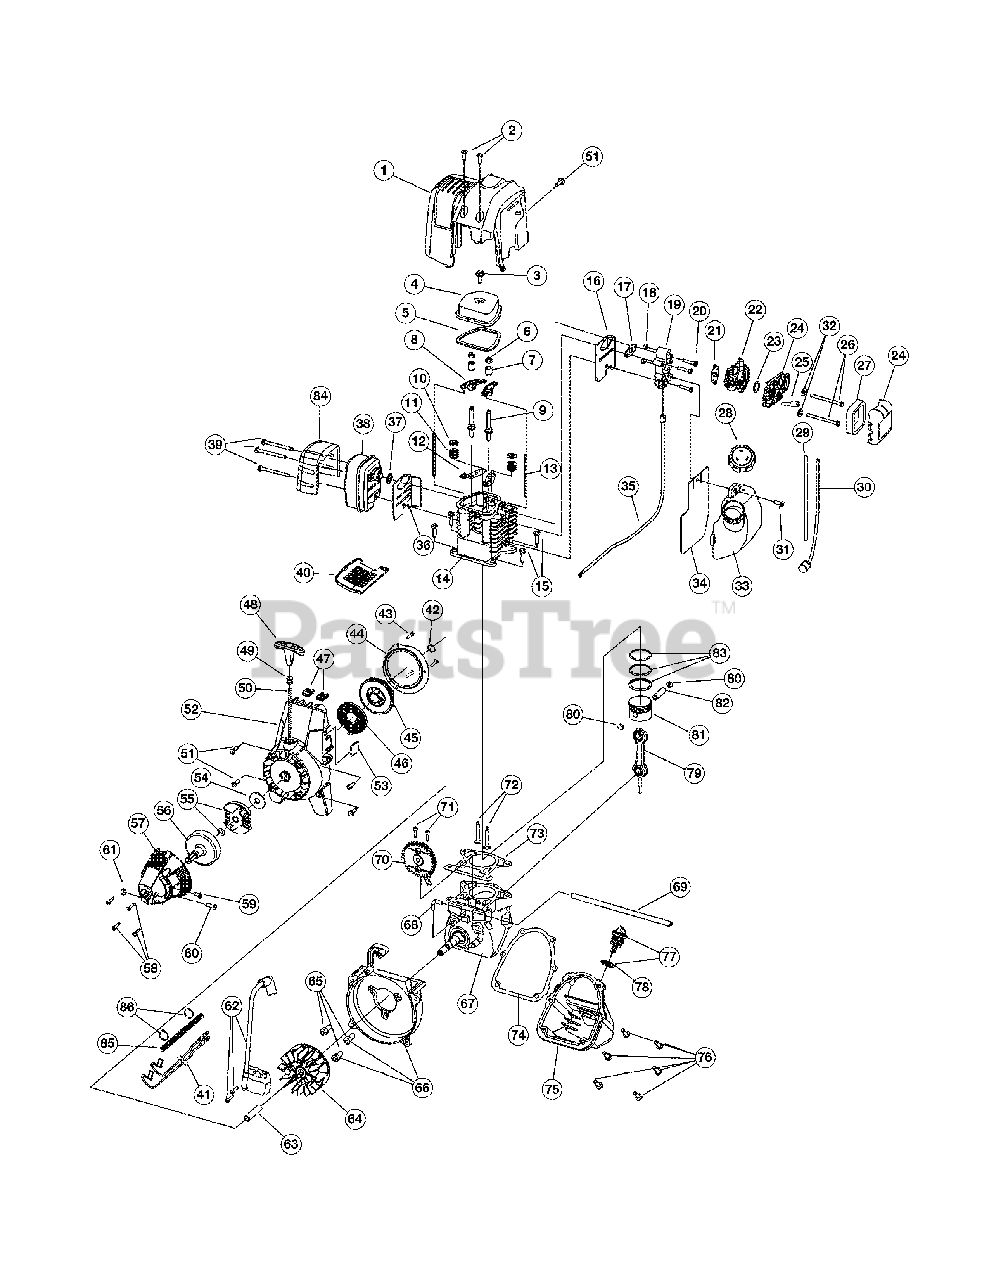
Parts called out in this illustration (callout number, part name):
1	Engine Cover
2	Engine Cover Screws
3	Valve Cover Screw
4	Valve Cover
5	Valve Cover Gasket
6	Rocker Adjustment Nut
7	Rocker Arm Pivot
8	Rocker Arm
9	Rocker Arm Stud
10	Valve Spring Retainer
11	Valve Spring
12	Push Rod Guide
13	Push Rod
14	Cylinder Assembly
15	Cylinder Screw
16	Intake Baffle Gasket
17	Carburetor Mount Gasket
18	Nut
19	Carburetor Mount
20	Carburetor Mount Screw
21	Carburetor Gasket
22	Carburetor w/Primer
23	O-Ring, Carburetor
24	Air Filter Cover Assembly
25	Breather Tube
26	Air Filter Mounting Screw
27	Air Filter
28	Fuel Cap
29	Fuel Return Line
30	Fuel Pick-Up Line with Filter
33	Fuel Tank Assembly
34	Fuel Tank Shield
35	Throttle Cable
36	Muffler Baffle
37	Muffler Gasket
38	Muffler
39	Muffler Mounting Screw
40	Muffler Cover
41	Switch Wire Assembly
42	Palnut
43	Plate Screw
44	Pressure Plate Assembly
45	Recoil Pulley Assembly
46	Recoil Spring
47	Nut Clip
48	Pull Handle
49	Rope Guide
51	Housing Screw
52	Starter Housing Assembly
53	Wire Grommet
54	Clutch Washer
55	Clutch w/Spacer
56	Clutch Drum
57	Clutch Cover Assembly
58	Cover Screw
59	Anti-Rotation Screw
62	Ignition Module with Screws
64	Flywheel
66	Shroud Assembly
67	Crankcase Assembly
68	90° Elbow
69	Breather Hose
70	Cam Bracket Assembly
71	Cam Bracket Screw
72	Valves, Intake and Exhaust
73	Cylinder Gasket
74	Pan Gasket
76	Pan Screw
77	Dipstick Assembly
79	Connecting Rod
80	Wrist Pin Button
81	Piston
82	Wrist Pin
83	Piston Ring Set
84	Heat Shield
85	Wire Lead Cover
